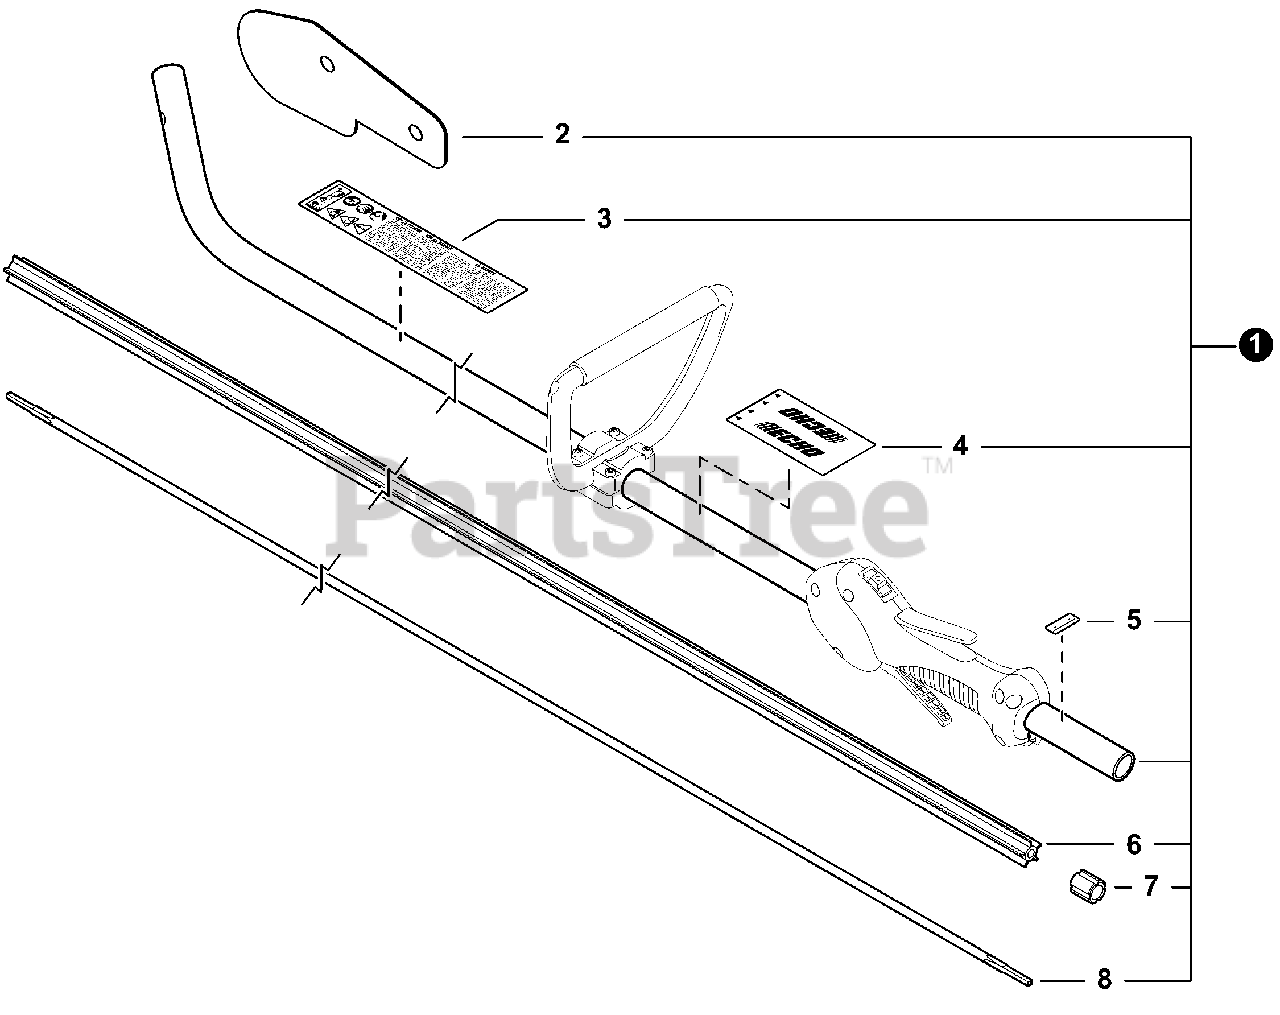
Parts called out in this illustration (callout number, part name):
1	MAIN PIPE KIT
2	PLATE, SHIELD
3	LABEL, CAUTION
4	LABEL, HANDLE LOCATION
5	LABEL - ALIGNMENT
6	LINER, FLEXIBLE 21.6×1420
8	DRIVESHAFT - FLEXIBLE
